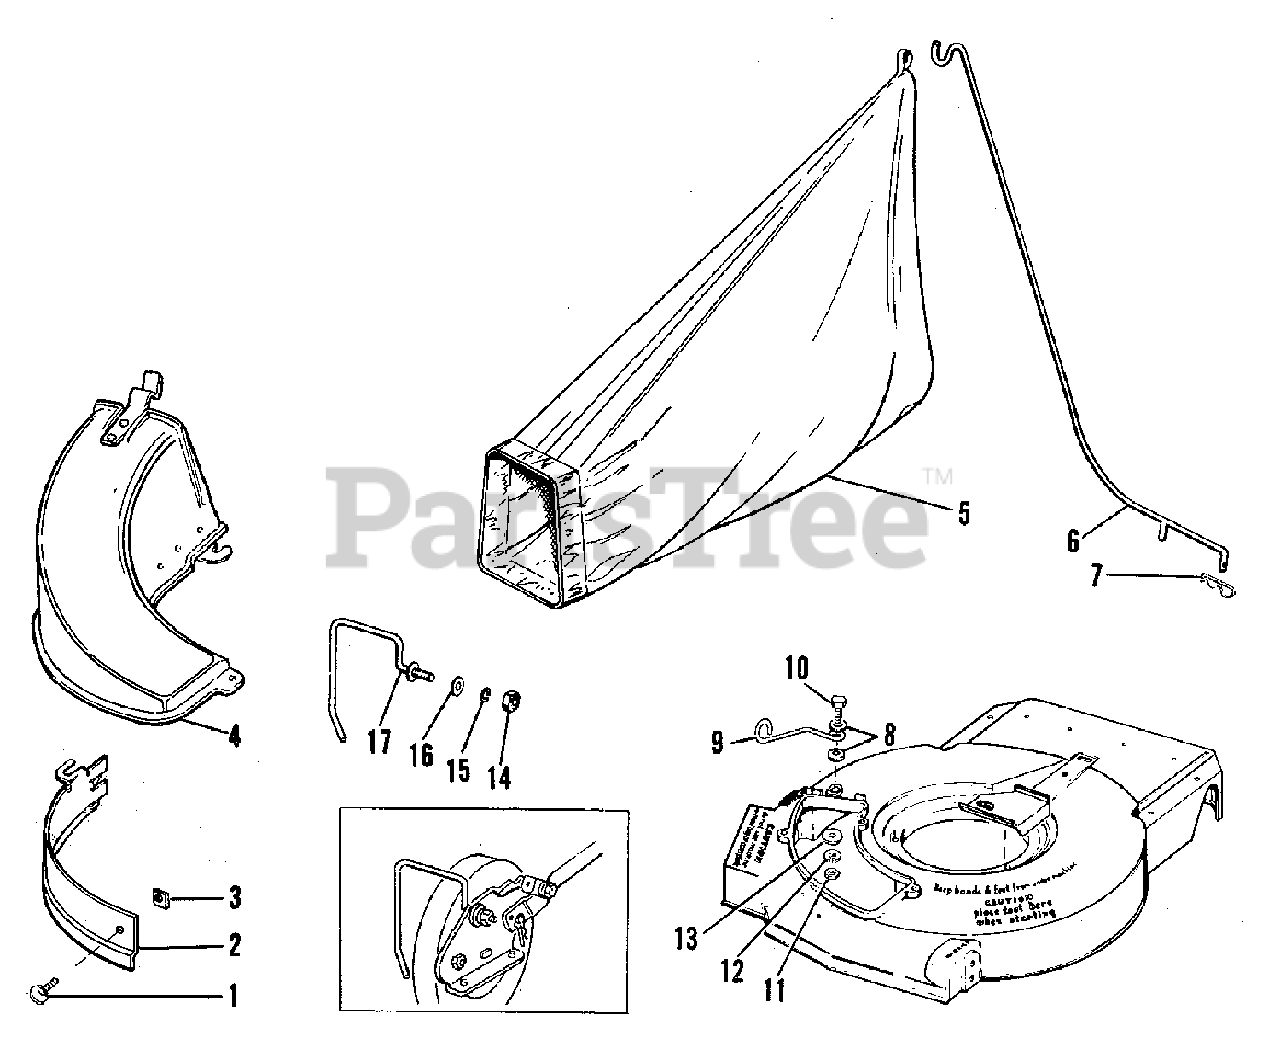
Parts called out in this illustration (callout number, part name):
1	SCREW, Thumb, 1/4-20 x 5/8
6	ROD, Bag Support
7	CLIP, Spring
8	WASHER, Flat, 1/4
10	SCREW, Hex Cap
11	NUT, Hex, 1/4-20
12	WASHER, Lock, 1/4
14	NUT, Hex, 5/16-18
15	WASHER, Lock, 5/16
16	WASHER, Flat, 5/16
